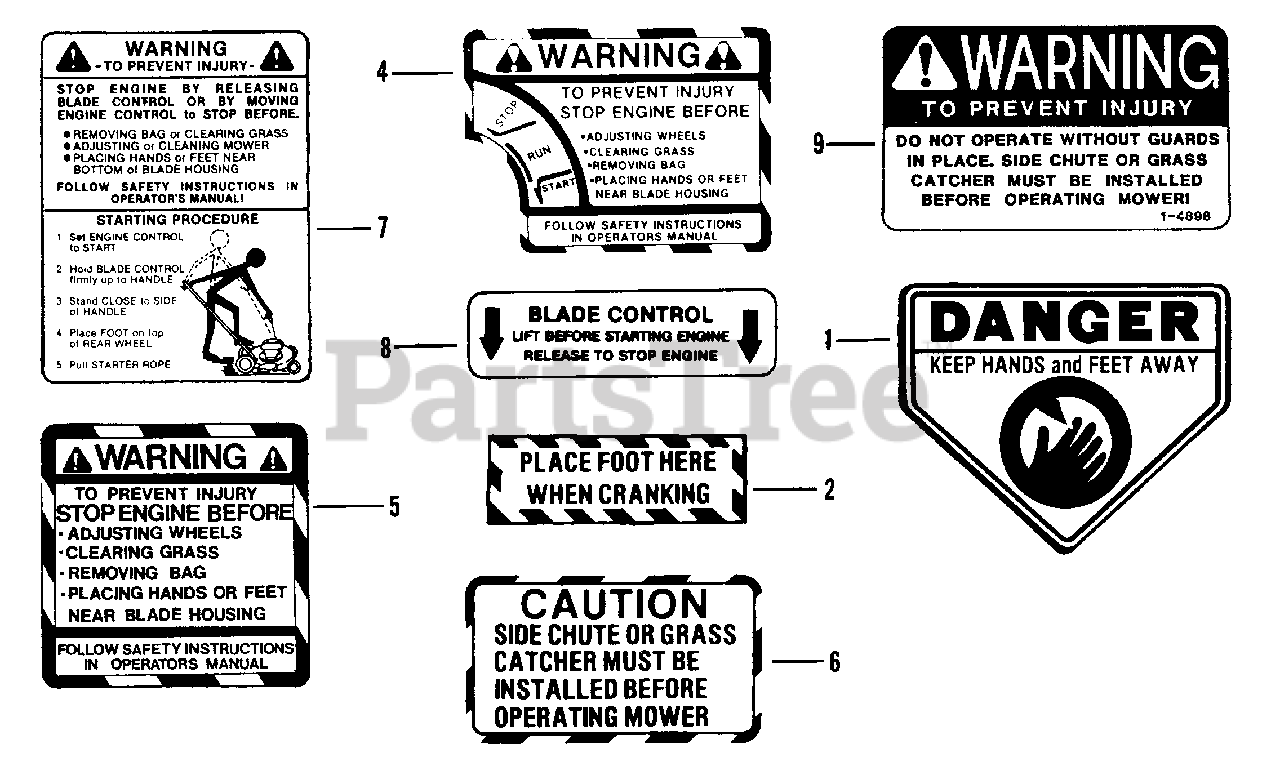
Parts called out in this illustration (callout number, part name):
1	DECAL, Danger (Keep Hands & Feet Away)
2	DECAL, Cranking
4	DECAL, Stop Warning
5	DECAL, Stop Warning
6	DECAL, Caution (Side Chute-Grass Catcher)
7	DECAL, Start-Stop
8	DECAL, Blade Control
9	DECAL, Warning - Discharge Opening
